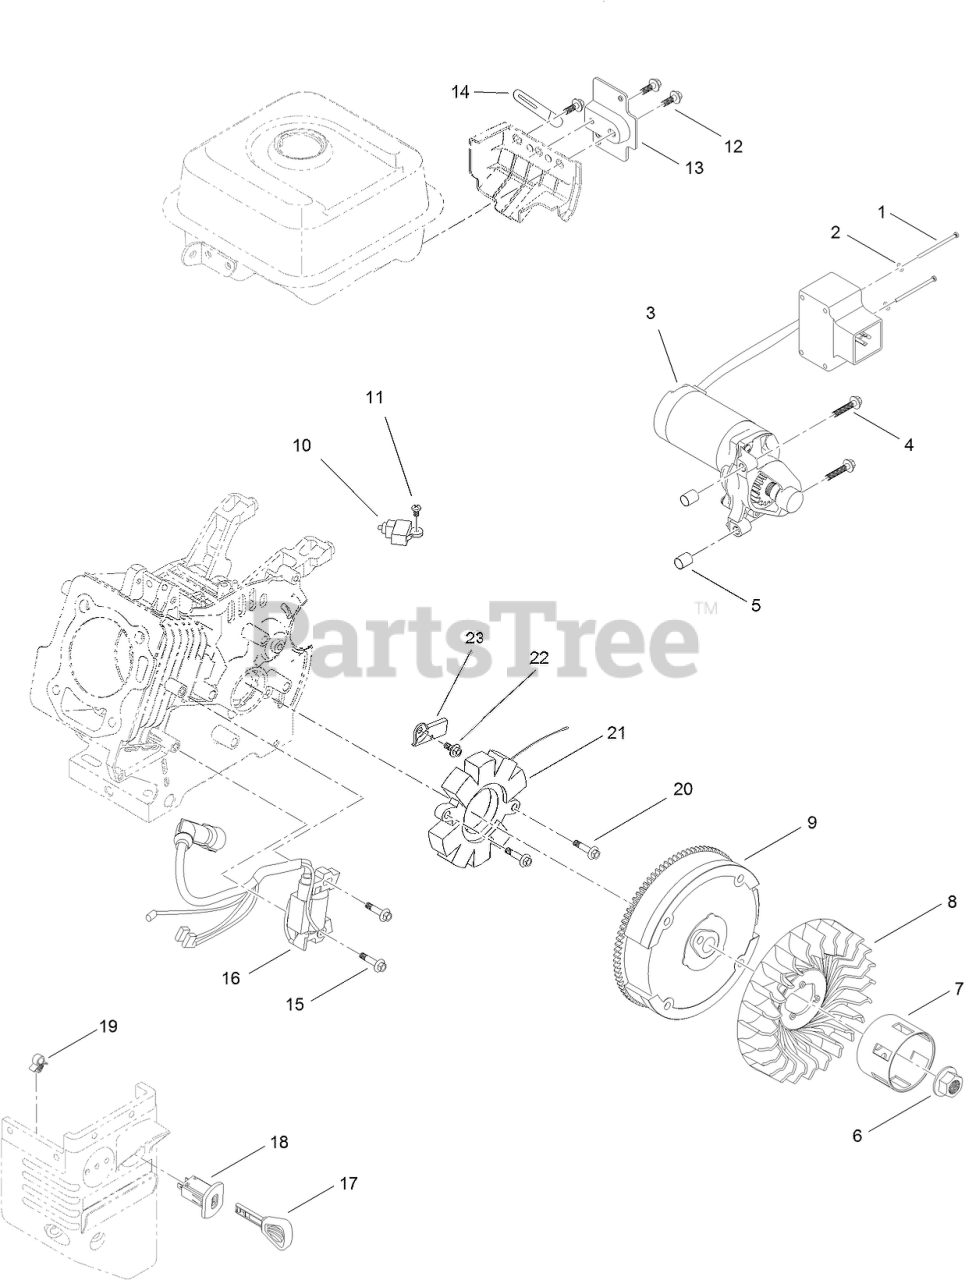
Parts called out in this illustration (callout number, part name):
1	SCREW-BHP
2	WASHER-PLAIN
3	MOTOR-STARTER
4	SCREW-FLANGE
5	PIN-DOWEL
6	NUT-FLANGE
7	CUP-STARTER
8	FAN-COOLING
9	FLYWHEEL AND RING GEAR ASM
10	SWITCH-KILL, ENGINE
11	SCREW-PPH
12	SCREW-HHF
13	BRACKET-SWITCHBOX, STARTER
14	CLIP-HARNESS, WIRE
15	SCREW-HHF
16	IGNITION COIL ASM
18	SWITCH-KEY
20	SCREW-HHF
21	ALTERNATOR
22	SCREW-HHF
23	CLAMP-WIRE, CHARGE
